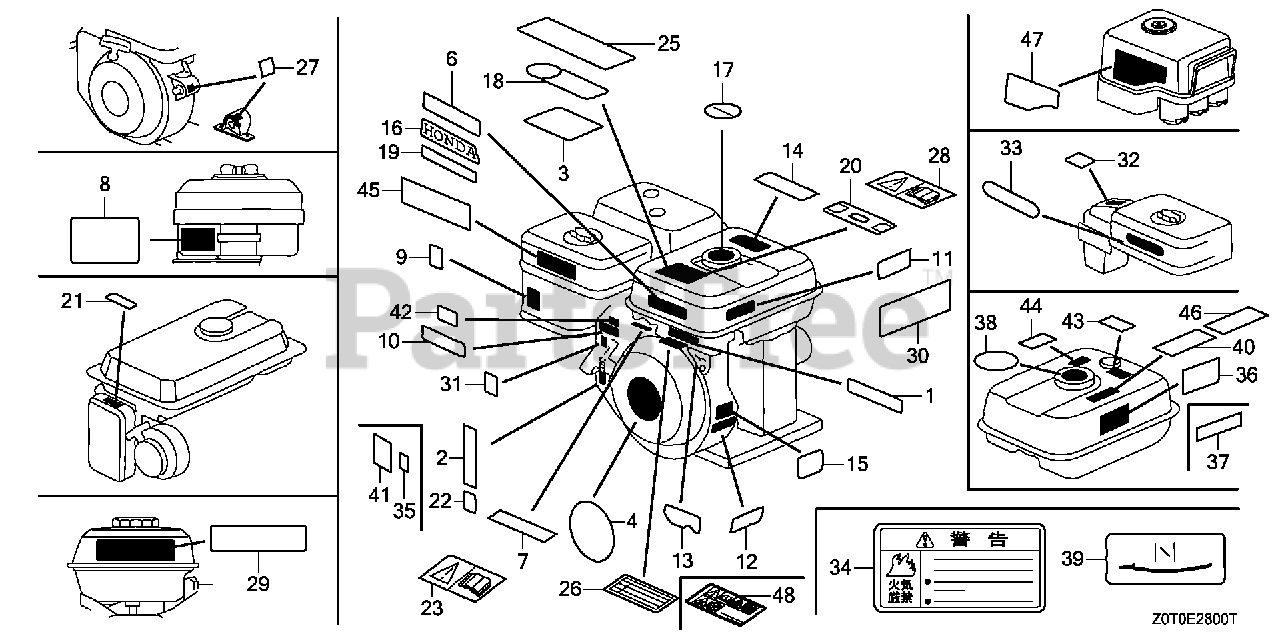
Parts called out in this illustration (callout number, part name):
4	EMBLEM (GX160)
9	MARK, CHOKE
22	LABEL, WARNING (NOT CERTIFIED FOR SALE)
36	MARK, OPERATOR CAUTION (ENGLISH)(MADE IN THAI)
44	MARK, EX. CAUTION (ENGLISH)
45	MARK, SALES POINT
